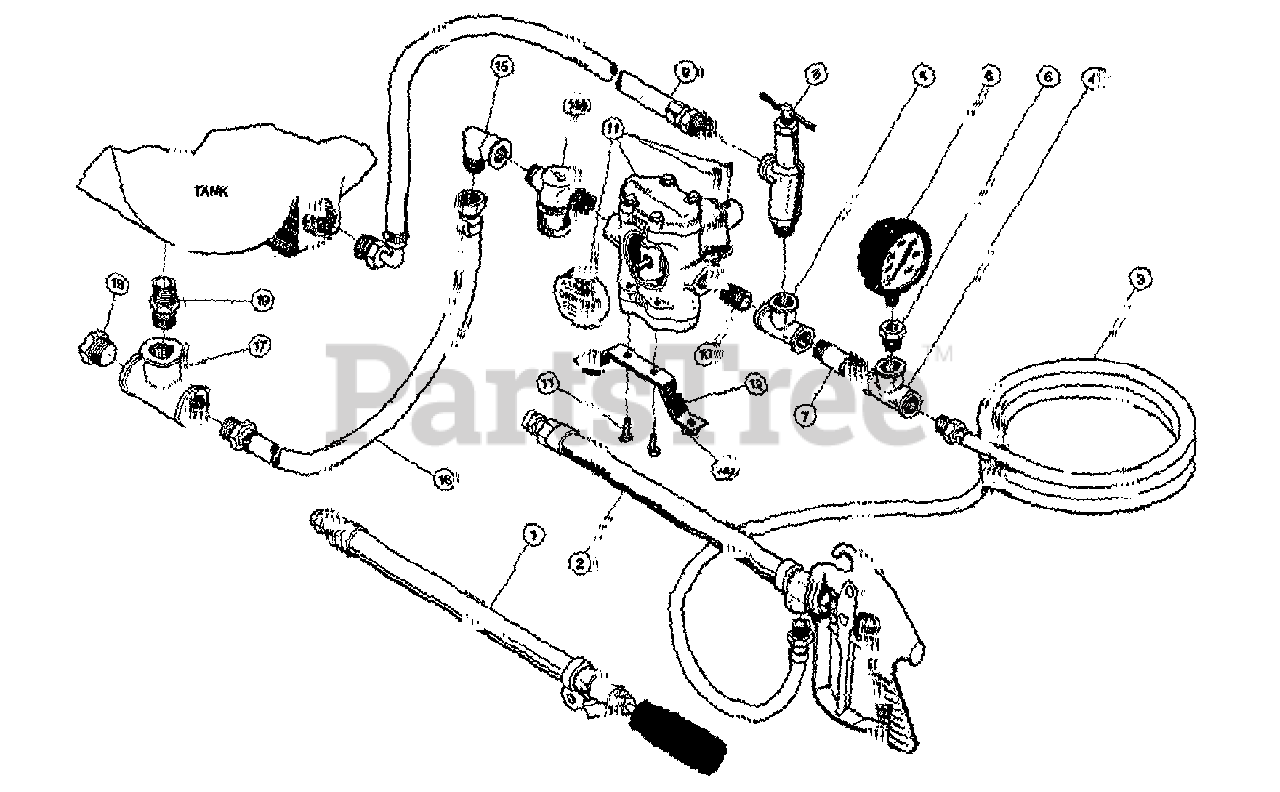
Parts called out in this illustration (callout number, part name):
1	GUN-TWIST SPRAY W143BR1/2
2	GRIP-PISTOL W43H6BR SPRAY GUN
3	HOSE-3/8 X 25' W2075660
4	TEE-1/2" PIPE W20983014
5	PIPE-BUSHING REDUCING
6	GAUGE-GLYCERINE PRESS WLFS220
7	NIPPLE-PIPE 50X2 GALVANIZED
8	VALVE PRESS.
9	HOSE-RETURN LINE W2075603
10	NIPPLE-1/2" CLOSE W20981014
11	PUMP-TWIN PISTON
12	ARM-TRQ 25G SPRAY W28200028
13	BUMPER-RUBBER TORQUE ARM
14	STRAINER W33500079
15	ELBOW-1/2" STREET WSE12
16	HOSE-17" SUCTION W2075661
17	TEE-3/4 PIPE NYL WTT34
18	PLUG-3/4" PLASTIC WF3400
19	NIPPLE-3/4 CLOSE WM1400
